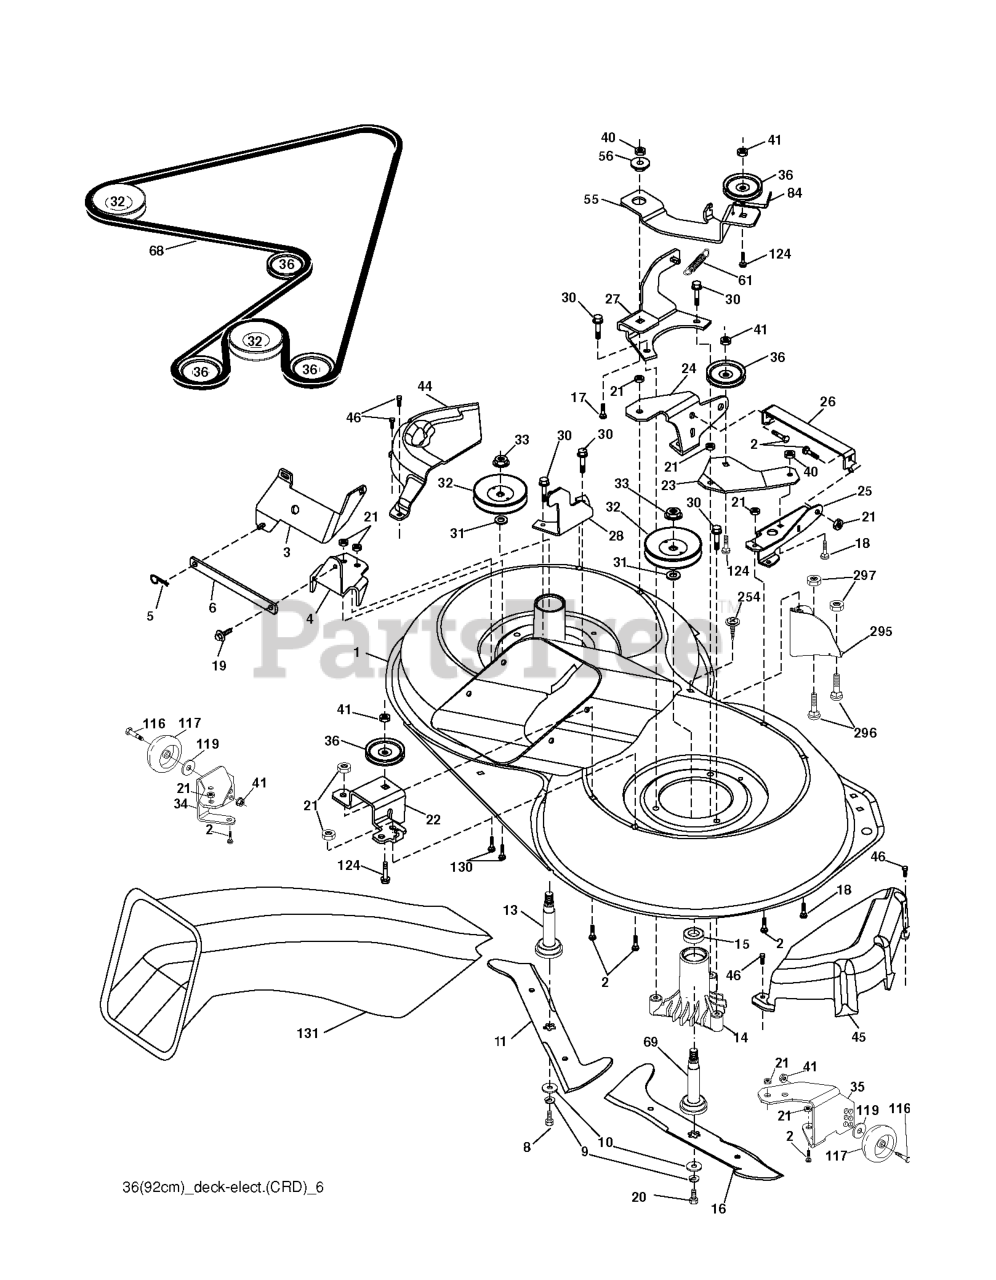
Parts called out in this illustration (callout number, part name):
2	RP BOLT 5/16-18 X3/4 ZN/YEL GR
5	RETAINER-SPRNG RB
6	BAR.SWAY.92.CRD
8	BOLT.3/8-24X1.25 GR8
9	LOCKWASHER
10	WASHER.BLADE
13	SHAFT ASM VENT
14	HOUSING.MANDREL.VENTED (MACHD)
17	BOLT.3/8-14X1.25
19	BOLT SHD 5/16-18
20	BOLT.3/8-24X1.25GR8. LHTHRD
21	LOCKNUT
26	SUPPORT
30	SCREW, WASHER HEAD
31	WASHER.SPACER.MANDREL
32	PULLEY MANDREL
33	NUT.FLANGE.LOCK.TOP
36	PULLEY.IDLER.4.25
41	NUT LOCK FLG 3/8-16 UNC
45	COVER.MANDREL.RH.CRD
46	SCREW.1/4-20X5/8
55	ARM.IDLER.92 CRD.2006
56	SPACER.RETAINER.MOWER
61	SPRING
68	BELT.DRIVE.92CM.CRD.2006
69	SHAFT.ASM.W/LWR.BRG.RH.THREAD
84	KEEPER, BELT IDLER
116	BOLT.SHOULDER.3/8-16X3-5/8.
117	RP WHEEL. GUAGE RALLY
118	NUT LOCK FLG 3/8-16 UNC
119	WASHER
124	BOLT.3/8-16X1.50
130	BOLT.CARR.SQNK.5/16-18UNC.X3/4
131	CHUTE BAGGER
254	SCREW 3/8-16X1
296	BOLT
297	NUT CENTERLOCK
